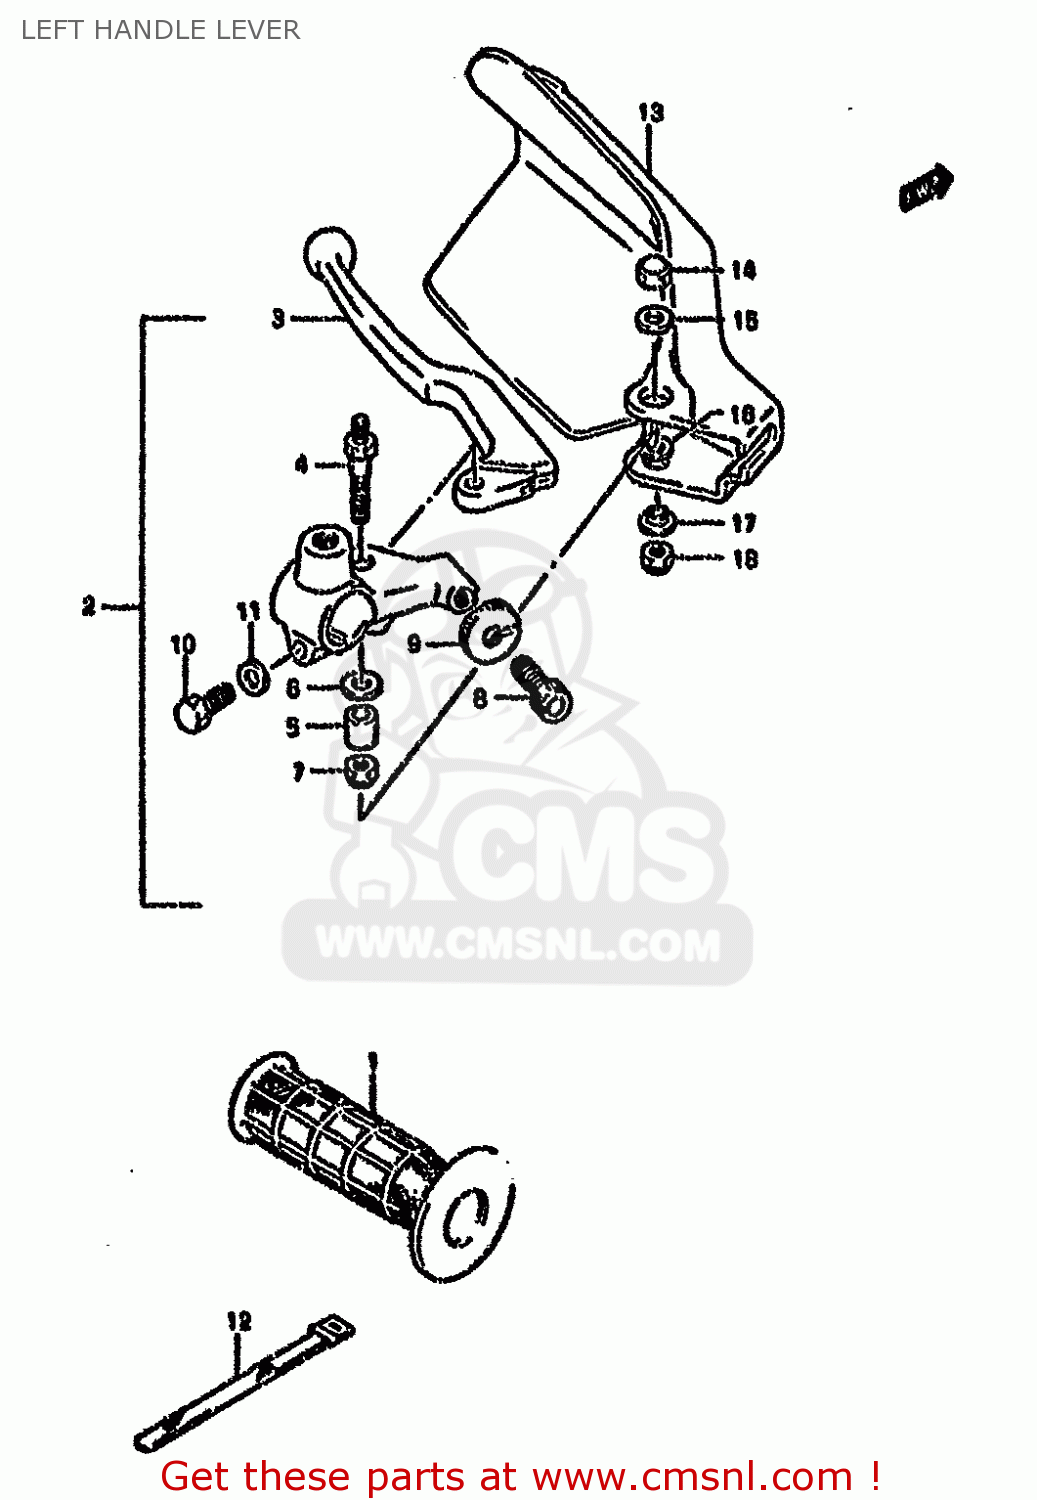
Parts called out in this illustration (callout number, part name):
1	GRIP,L
2	LEVER ASSY,CLUTCH
3	LEVER,CLUTCH
4	BOLT,LEVER SET
5	SPACER,LEVER SET
6	WASHER,LEVER SET
7	NUT
8	ADJUSTER,CABLE
9	NUT,LOCK
10	BOLT
11	WASHER
12	CLAMP(L:120)
13	COVER,KNUCKLE,L
14	NUT
15	WASHER(6.5X20X1.6)
16	WASHER(6.5X16X1.2)
17	WASHER
18	NUT 6MM
